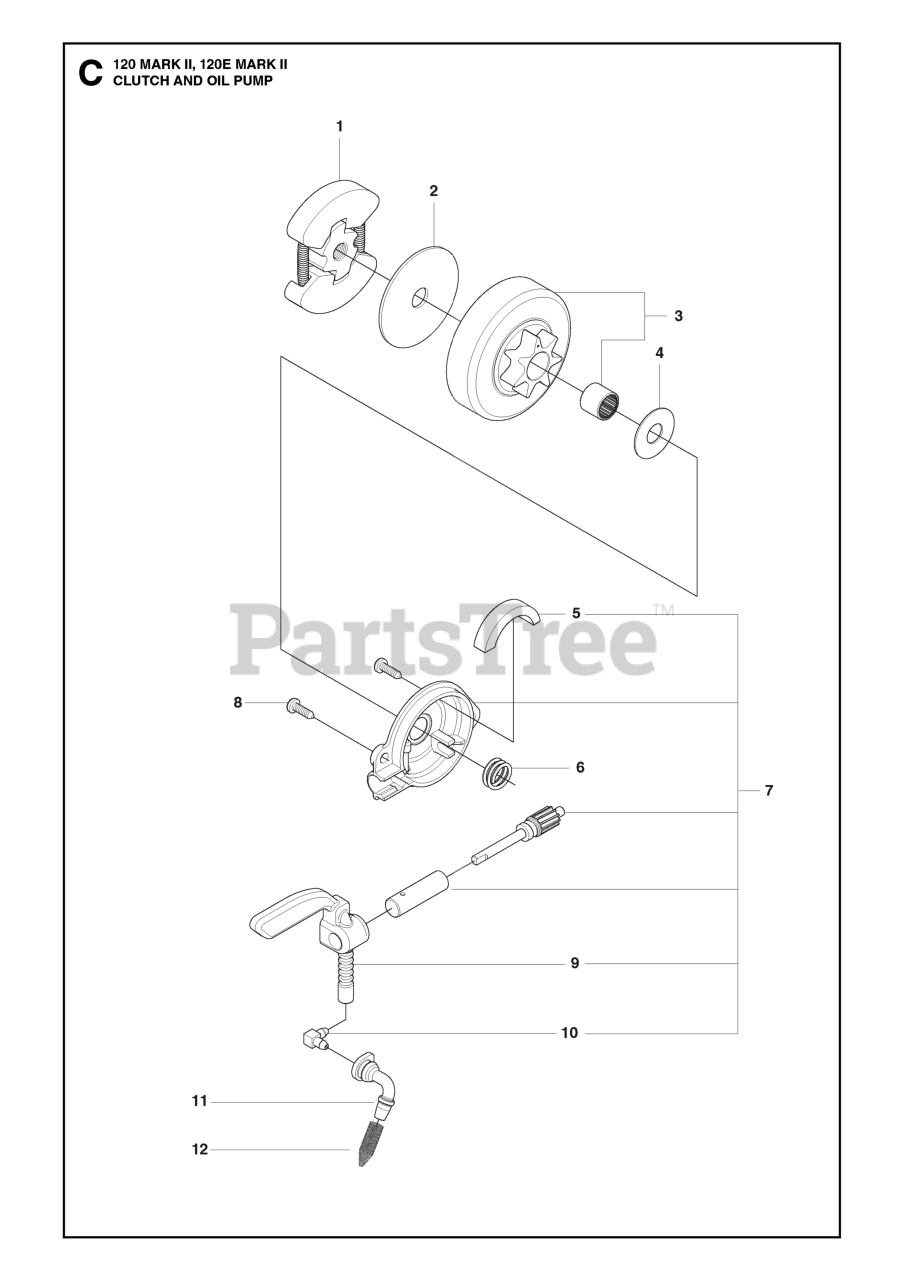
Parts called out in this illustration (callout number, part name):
1	CLUTCH ASSEMBLY
2	FRICTION DISC,CLUTCH 36/41
3	CLUTCH DRUM ASSY
4	WASHER
5	SEAL
6	WORM GEAR
7	OIL PUMP ASSY
8	SCREW 6-19X.437
9	BLOCK OIL
10	ELBOW
11	SEAL PICKUP
12	SCREEN/FILTER
